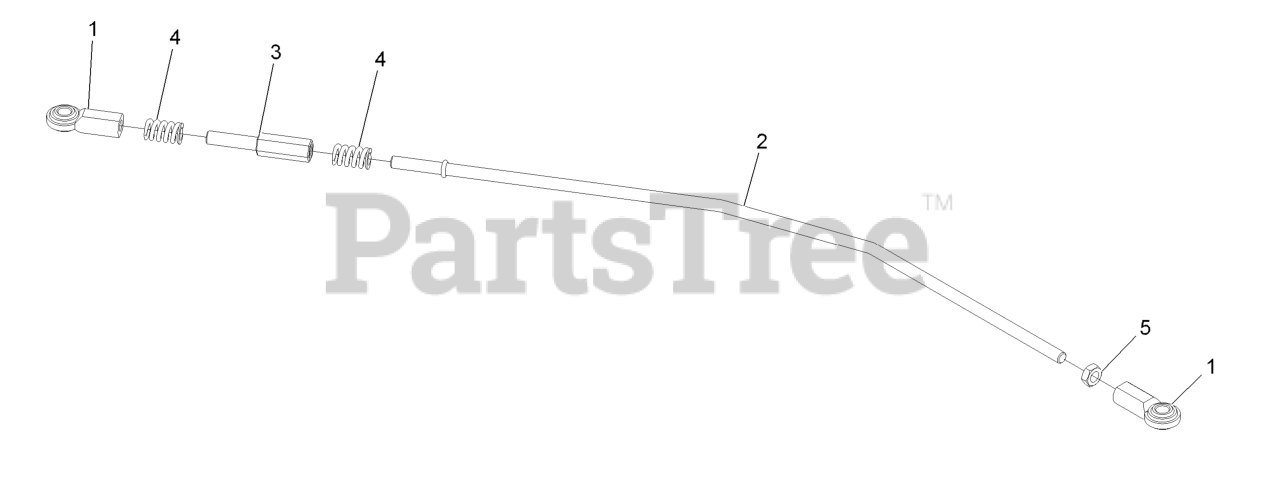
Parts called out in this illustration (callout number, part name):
1	Balljoint
2	Link-Lower,Motion Control
3	Rod-Adjustment
4	Spring-Compression
5	Nut-Jam 3/8-24
